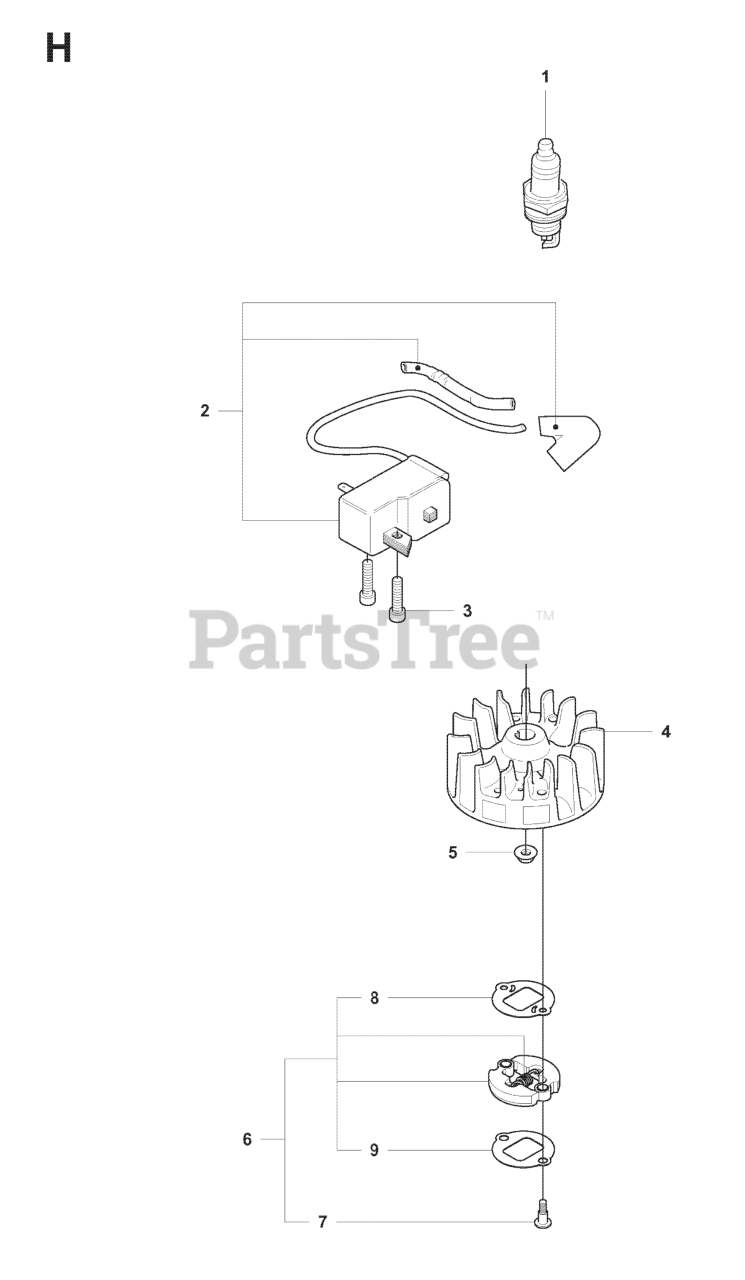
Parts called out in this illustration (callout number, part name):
1	SPARK PLUG RCJ6Y NLA
2	IGNITION MODULE MB50
4	FLYWHEEL
5	FLANGE NUT
6	CLUTCH CPL
